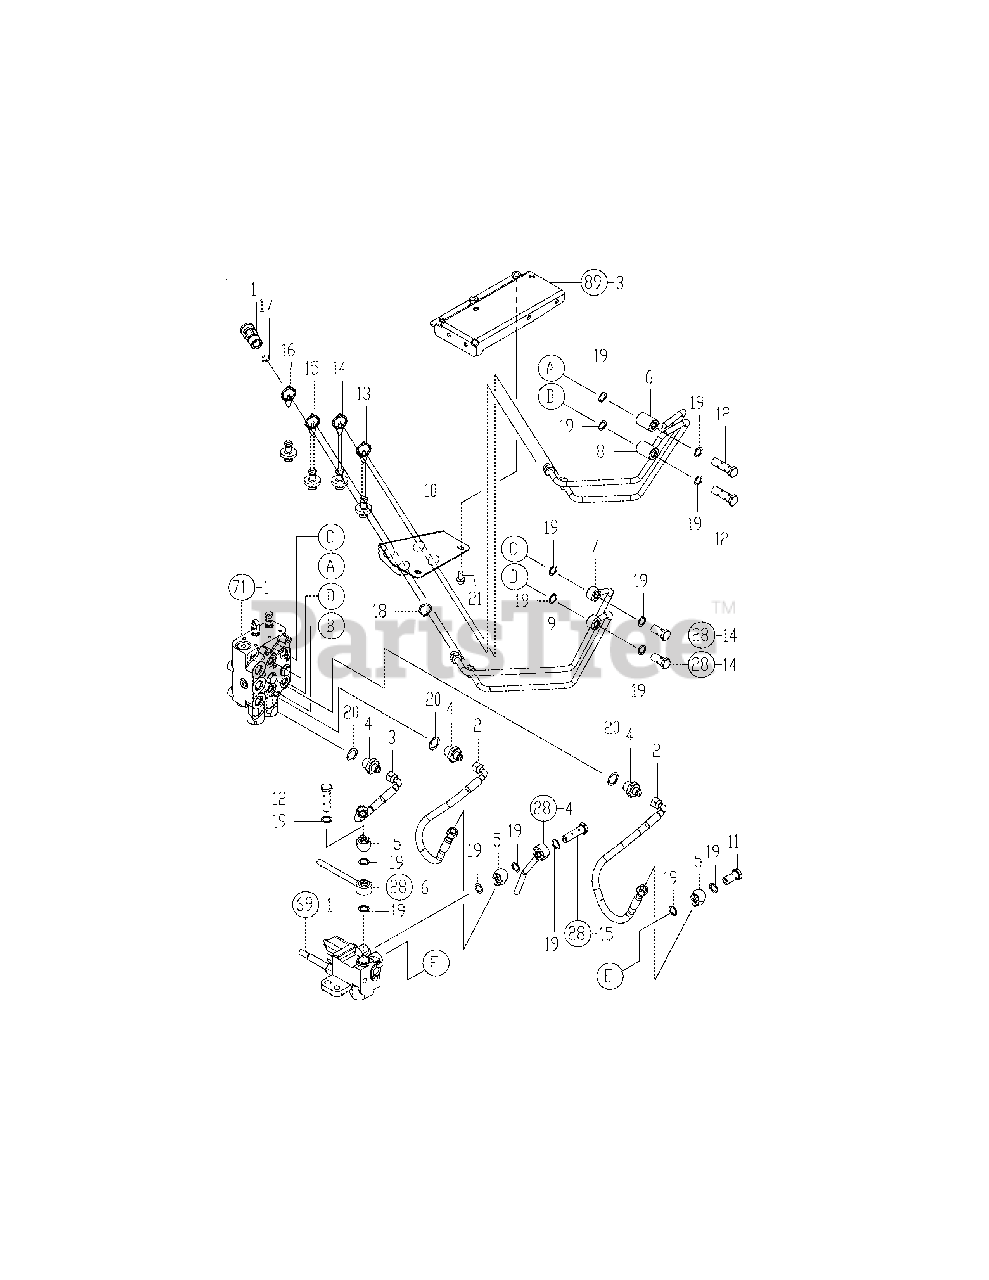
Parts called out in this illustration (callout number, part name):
1	Coupler, Hyd.Quick
4	Joint3/4Unf-9/16Unf
5	Joint9/16Unf-14.5
6	Hp Pipe Cmp, Scv A1
7	Hp Pipe Cmp, Scv A2
8	Hp Pipe Cmp, Scv B1
9	Hp Pipe Cmp, Scv B2
10	Stay(Scv Coupler
11	Ball Joint Bolt 9/16
12	Ball Joint Bt L 9/16
13	Plug, Dust Red
14	Plug, Dust Blue
15	Plug, Dust Yellow
16	Plug, Dust Green
19	Gasket, 14 X 1.0
20	Gasket, 19 X 1.0
